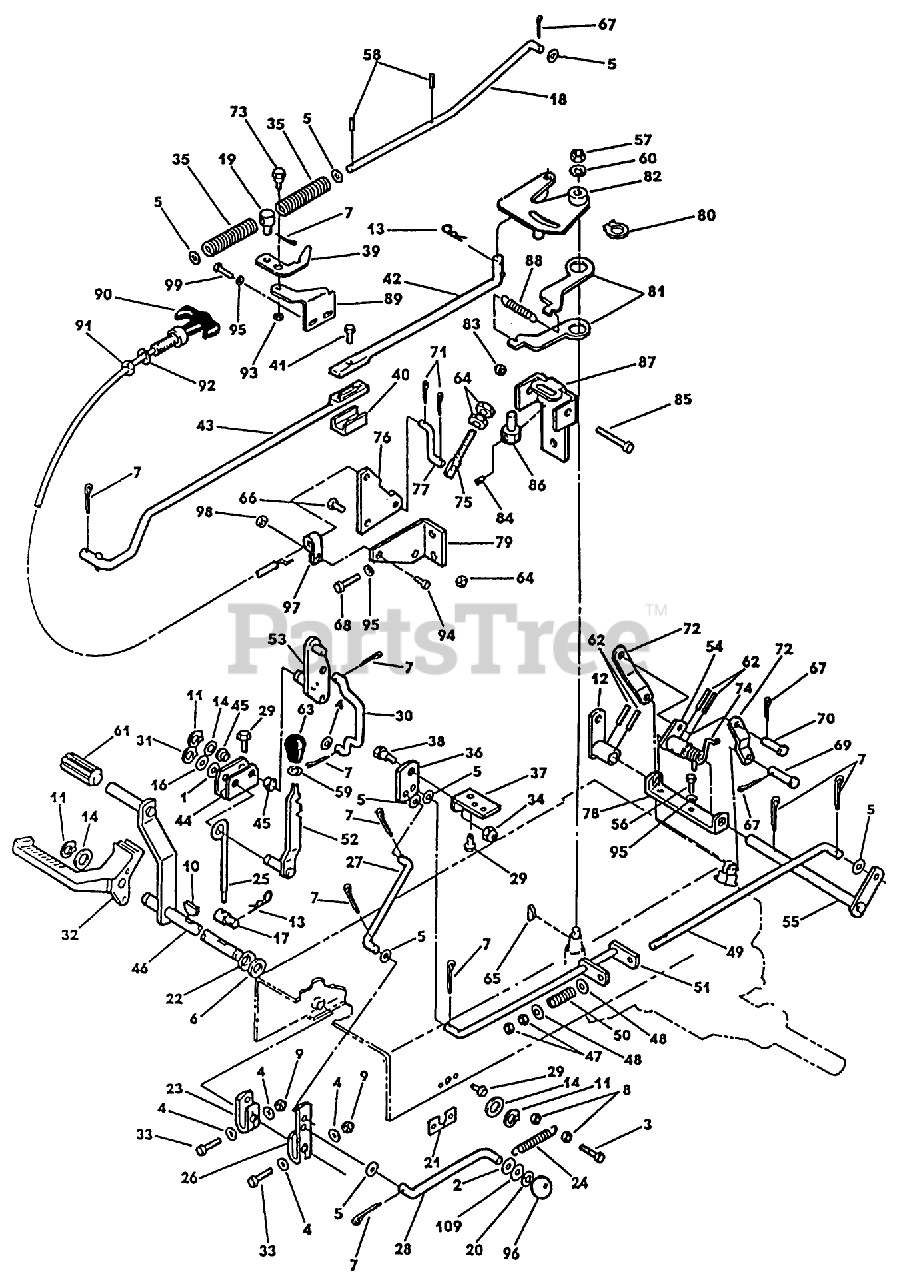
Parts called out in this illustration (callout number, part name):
9	NUT-LOCKING
13	PIN-HAIR
22	WASHER-CUPPED
31	RING - RETAINING
37	BRKT-BRAKE PIVOT
50	SPRING-BRAKE
52	CRUISE RELEASE AY.
56	SCREW - HEX
68	SCREW-THD ROLL, HWH
73	BOLT-SHOULDER
74	SPRING,TORSION
76	LEVEL - PIVOT
79	BRACKET,CABLE
80	RING - RETAINING
84	SETSCREW
88	SPRING-EXTENSION
89	BRACKET-LOCK
91	Nut, Hex Jam
